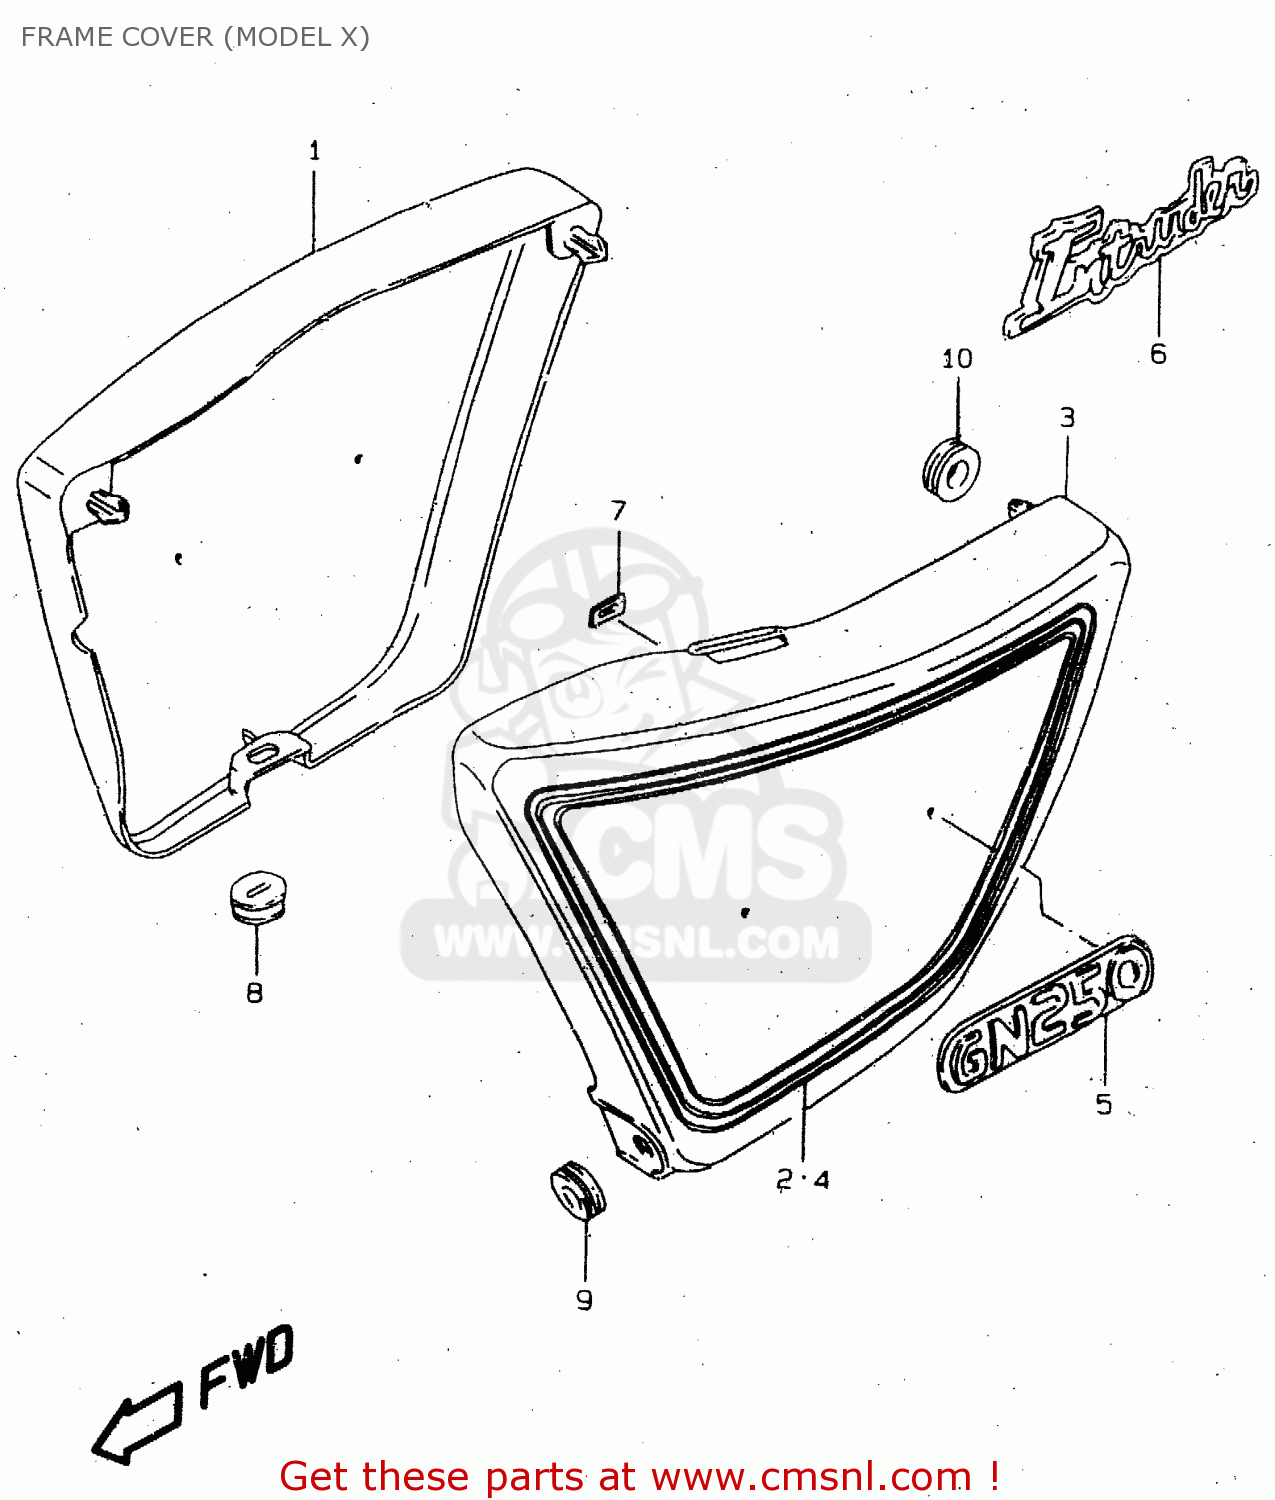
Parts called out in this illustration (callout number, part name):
1	COVER,FRAME,R(RED)
2	TAPE SET, RH
3	COVER,FRAME,LEFT
4	TAPE SET, LH
5	EMBLEM,GN250
6	EMBLEM,FRAME COVER
7	NUT
8	CUSHION
9	CUSHION
10	CUSHION
